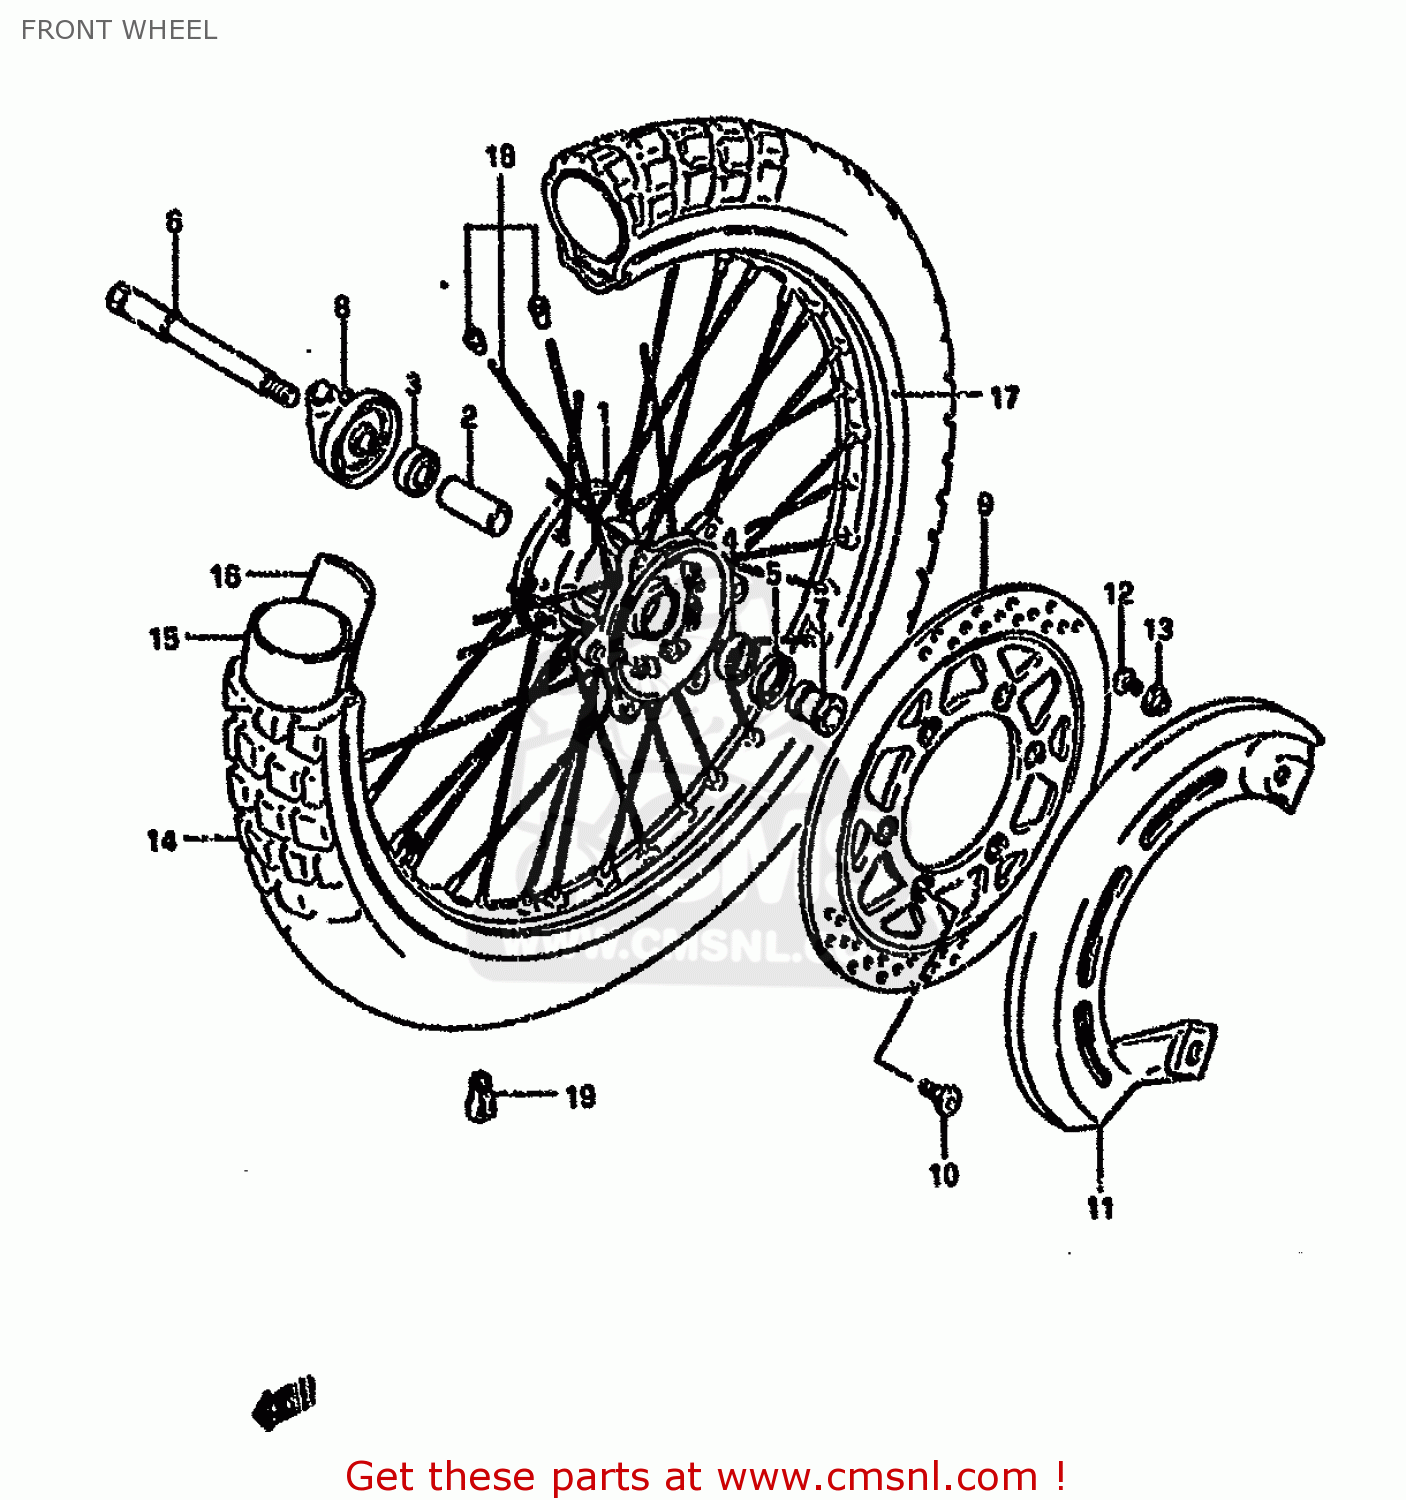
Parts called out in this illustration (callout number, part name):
1	HUB,FRONT
2	SPACER,FR HUB BEARING
3	BEARING
4	BEARING
5	SEAL,OIL(22X35X5)
6	AXLE,FR
7	SPACER,FR AXLE,L
8	BOX ASSY,SPEEDOMETER GEAR
9	DISC,FR BRAKE
10	BOLT,BRAKE DISC
11	COVER,FRONT BRAKE DISC
12	SCREW 6X12
13	WASHER
14	TIRE,FRONT 90/90-21 54
15	TUBE
16	PROTECTOR,WHEEL INNER
17	RIM,FR WHEEL(21X1.85)
18	SPOKE SET,FR WHEEL
19	BALANCER,WHEEL
